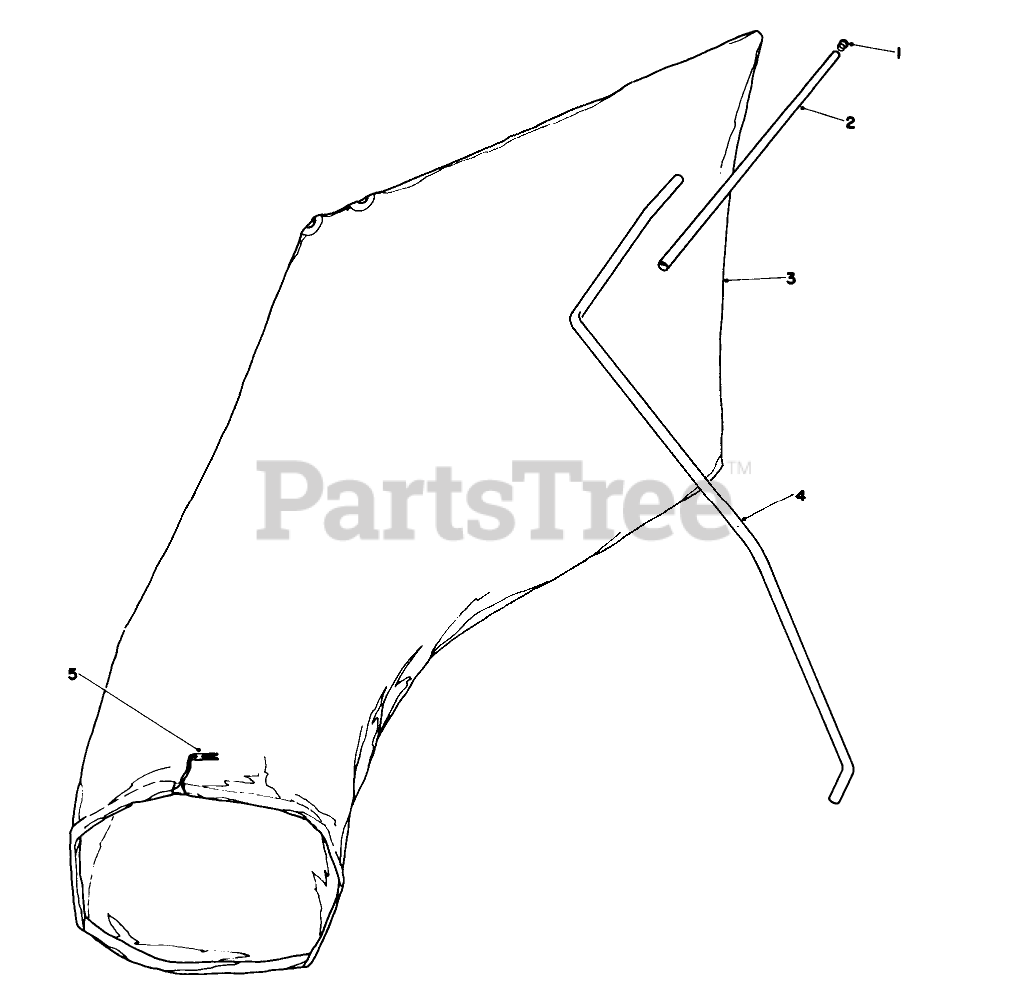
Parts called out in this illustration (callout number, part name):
2	BAG HANGER TUBE
3	Bag (Incl. Ref. #5)
4	HANGER ROD
5	BAG CORD FASTENER
